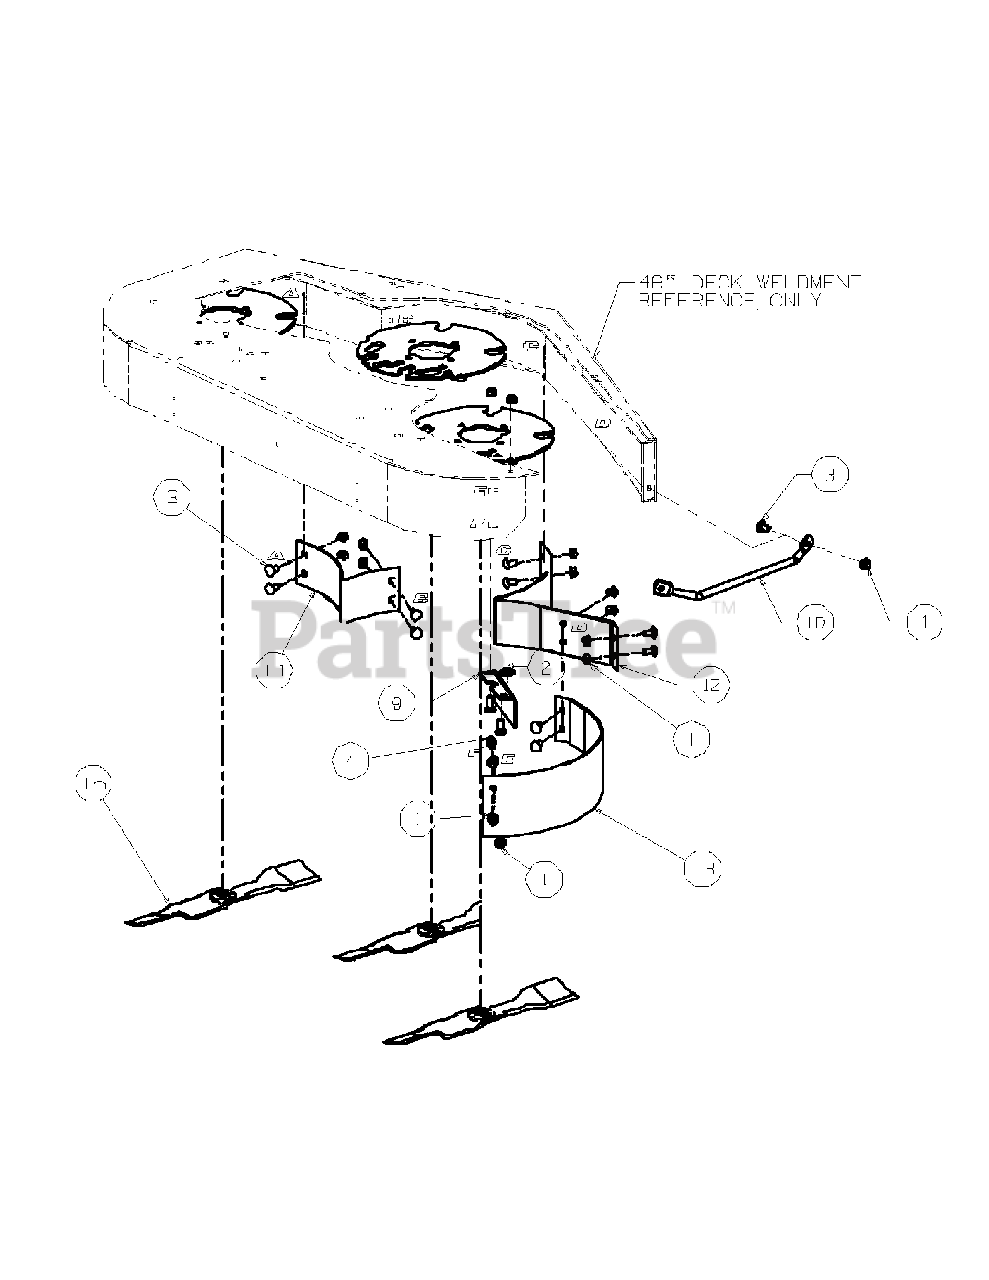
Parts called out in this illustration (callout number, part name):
1	NUT, HEX 3/8-16 FLG LOCK
2	WASHER, IDLER
3	BOLT, CARR 3/8-16 X .75 LG
4	BOLT, CARR 3/8-16 X 1.0 LG
9	BRKT, CHUTE, FAB DECK
10	GUARD, FINGER, FAB DECK
11	Baffle, MULCH, FAB 48 LH
12	Baffle, MULCH, FAB 48 CENTER
13	Baffle, MULCH, FAB 48 RH
15	BLADE, 17.0, MULCH, 0.756 ID
